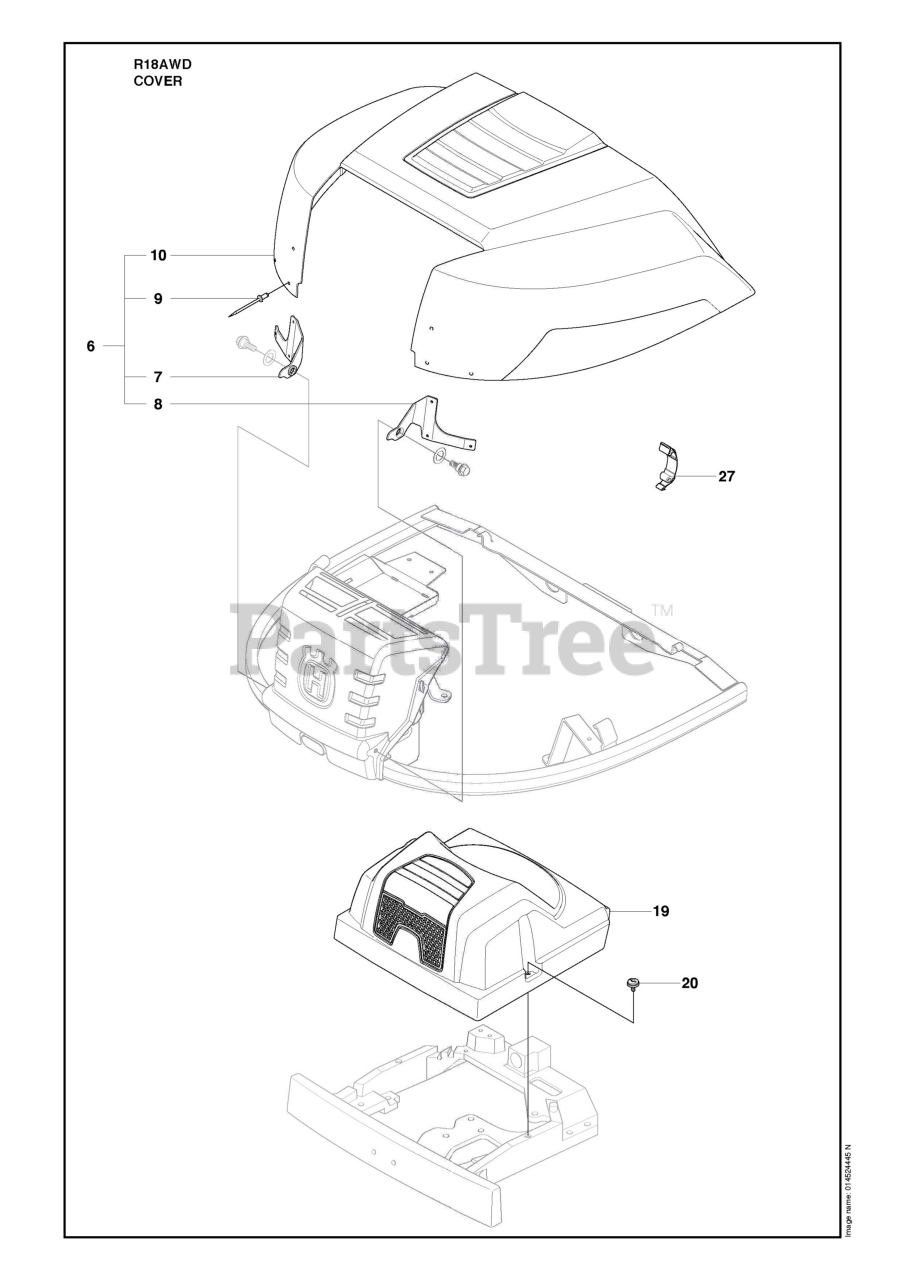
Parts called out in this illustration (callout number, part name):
1	FOOT PLATE
3	FOOT PLATE
6	ENGINE HOOD ASSY
10	ENGINE HOOD ASSY
13	CONTROL COVER
15	CONTROL COVER
19	COVER
26	PROTECTIVE COVER
27	CLIP GRAY
28	UNIT COVER
